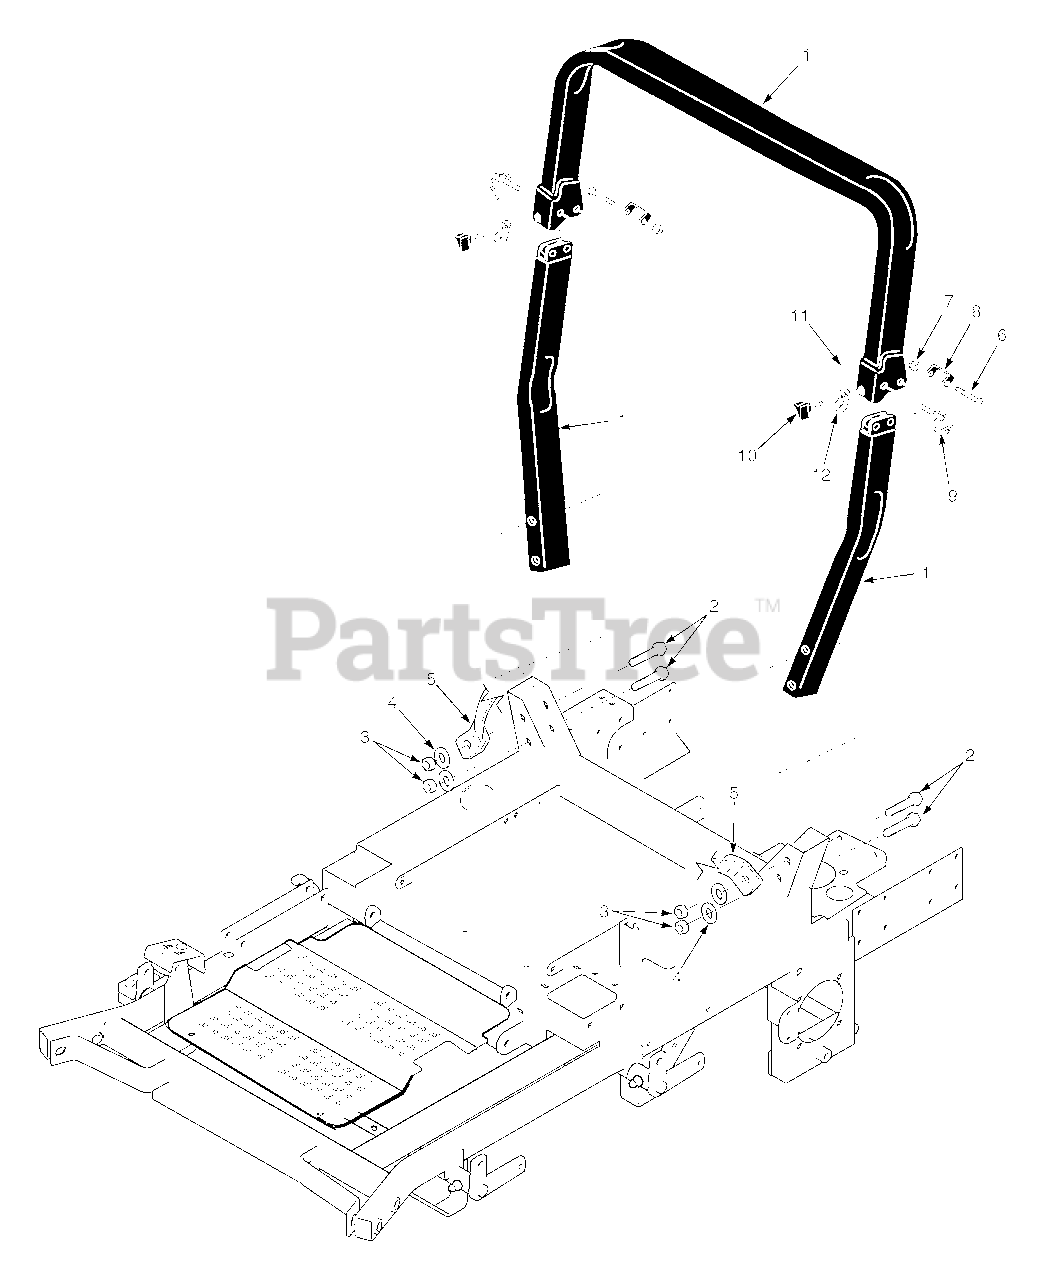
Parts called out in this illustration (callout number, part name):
1	STT, ROPS Acessory
2	Bolt, Hex Head 1/2-13 x 4-1/2"
3	Nut, Center Lock 1/2-13
4	Flatwasher, 1/2-.562 x 1.375 x .109
5	Seat Belt
6	Bolt, Hex Head 1/2-13 x 3-1/2"
7	Nut, Center Lock 1/2-13
8	Bracket, Stop
9	Pin
10	Thumb Screw, 5/16-18 NC x 3-4"
11	Hair Pin, Cotter
12	Clamp
